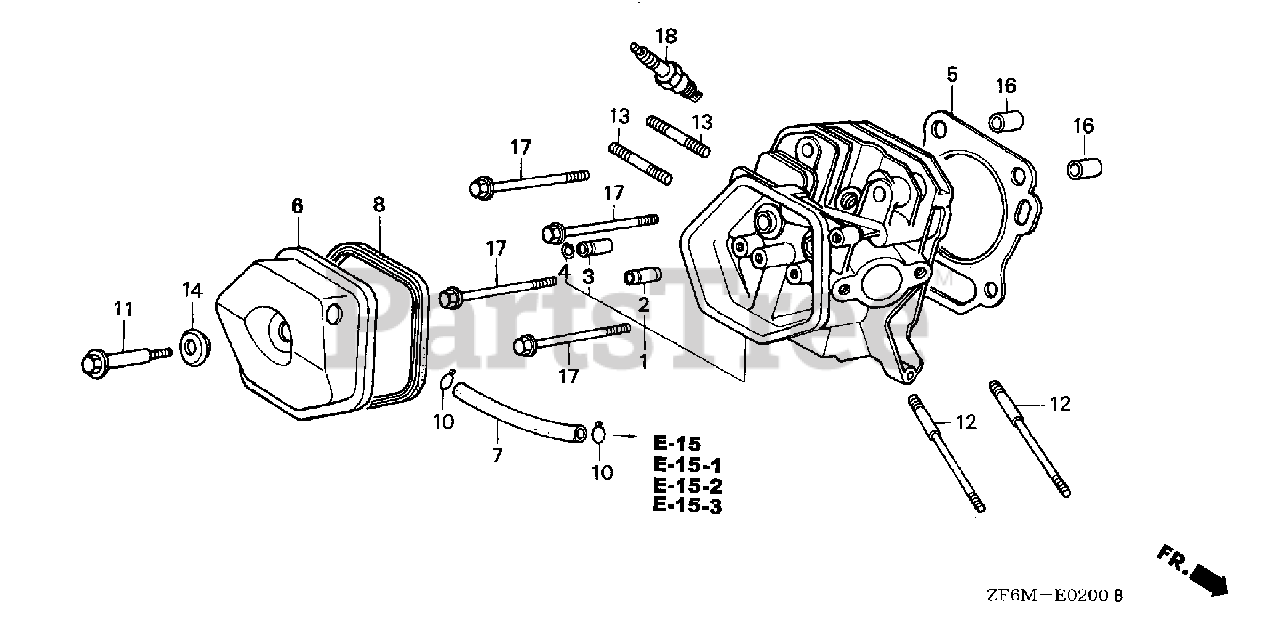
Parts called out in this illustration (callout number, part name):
1	CYLINDER HEAD
2	GUIDE, VALVE (OS)
3	GUIDE, EX. VALVE (OS)
4	CLIP, VALVE GUIDE
5	GASKET, CYLINDER HEAD
6	COVER, HEAD
7	BULK HOSE, VACUUM (11X1000) (11X105)
8	GASKET, CYLINDER HEAD COVER
11	BOLT, HEAD COVER
12	BOLT, STUD (8X131.5)
13	BOLT 2, STUD (8X32)
14	WASHER, HEAD COVER
16	PIN A, DOWEL (12X20)
17	BOLT, FLANGE (10X80)
18	SPARK PLUG (BPR5ES) (NGK)
18	SPARK PLUG (W16EPR-U) (DENSO)
18	SPARK PLUG (BPR6ES) (NGK)
18	SPARK PLUG (W20EPR-U) (DENSO)
